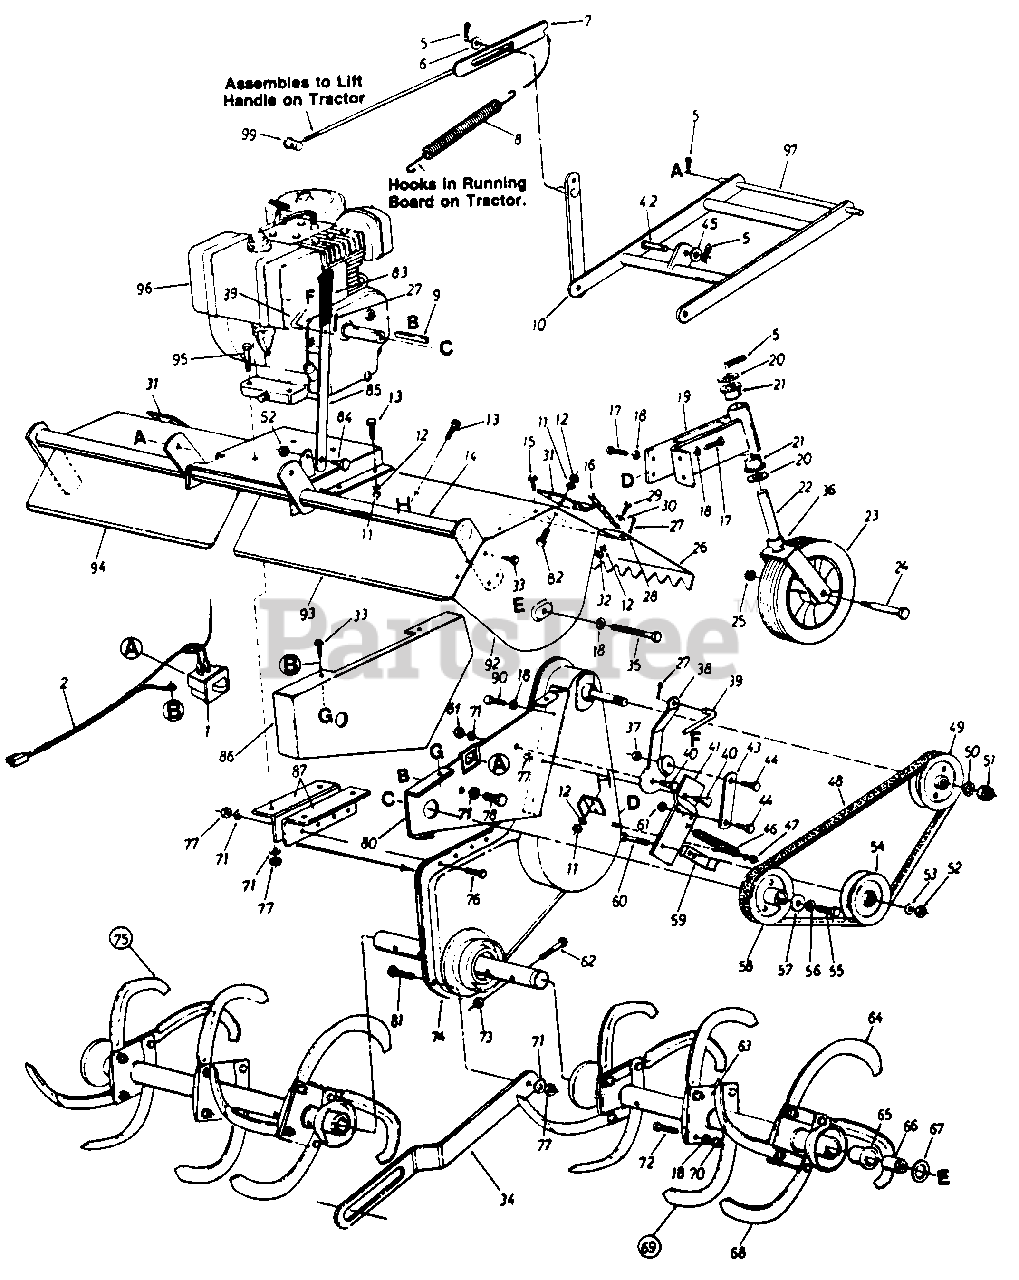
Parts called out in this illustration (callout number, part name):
1	Safety Switch
2	Wire Harness
5	Internal Cotter Pin
6	Fl-Wash. 1/2" I.D. x .93 O.D.
9	Sq. Key 1/4" x 1/4" x 2.00 Lg.
12	L-Wash. /" I.D.
13	Hex Bolt 1/J-28 x .62 Lg.'
16	#2 Dog Chain x 20" Lg.
17	Hex Wash. Hd. Self-Tap Scr. 3/8-24 x .75 Lg.
18	L-Wash. 3/8 I.D.
21	Flange Bearing 3/4 I.D. x 1.00 O.D.
24	Shoulder Bolt .623" I.D. x 3 62" Lg
25	Hex Cent. L-Nut 7/16-14 Thd.
28	L.H. Flap Rod
29	Hex Bolt 1/4-20 x .62 Lg.
30	Fl-Wash. 1/4" I.D.
33	Hex Wash. Hd. Selt-Tap Scr. 1/4 x .62n Lg.
36	Spacer 752n I.D. x 1.25n O.D.
37	Hex Cent. L-Nut 5/16-18 Thd.
40	Shoulder Bolt 7/16" Dia. x 1.75" Lg.
45	Fl-Wash. .50" I.D. x l.O" O.D. x .06
46	Exten8ion Spring .62 O.D. x 6.12" Lg.
47	Hex Crown Nut 3/8-24 Thd.
48	"V"-Belt (Kevlar)
49	1/2" "V"-Pulley 4.75" O.D. x .625" Bore
50	L-Wash. 5/8" I.D.
51	Hex Ins. L-Nut 5/8-18 Thd.
52	Hex Cent. L-Nut 3/8-16 Thd.
53	Fl-Wash. 3/8" I.D.
54	Idler Pulley 4.0" O.D.
55	Hex Bolt
56	L-Wash. 7/16" I.D.
57	Fl-Wash. 7/16" I.D. x 1.38n
58	1/2" "V"-Pulley .475' O.D. x 1.00" Bore
61	Hex Cent. L-Nut 5/16-18 Thd.
62	Hex Bolt 7/16-14 x 2.00" Lg.
66	Spacer
67	Thrust Wash. 1/2" I.D. x 1.55
71	L-Wash. 5/16 I.D.
72	Hex Bolt 3/8-24 x 1.5 Lg.
73	Hex Cent. L-Nut 7/16-14 Thd.
77	Hex Nut 5/16-18 Thd.*
78	Hex Bolt 5/16-24 x .62"
80	Clutch Support Bracket
81	Shld. Bolt .435 Dia. x .265 5/16-18 Thd.
82	Hex Bolt 1/4-28 x .75' Lg.
83	Plastic Grip
84	Shoulder Bolt .498 Dia. x .212 Lg.
96	8 H.P. Engine
97	Hitch Rod
99	Ferrule
04975-0637	PLATE ASSY-SIDE-LH - POWDER BLACK (0637)
04978-0637	SUPPORT-SWIVEL WHE - POWDER BLACK (0637)
04983-0637	L.H.-Tine Shield - POWDER BLACK (0637)
14298-0637	SHROUD-CLUTCH SUP - POWDER BLACK (0637)
